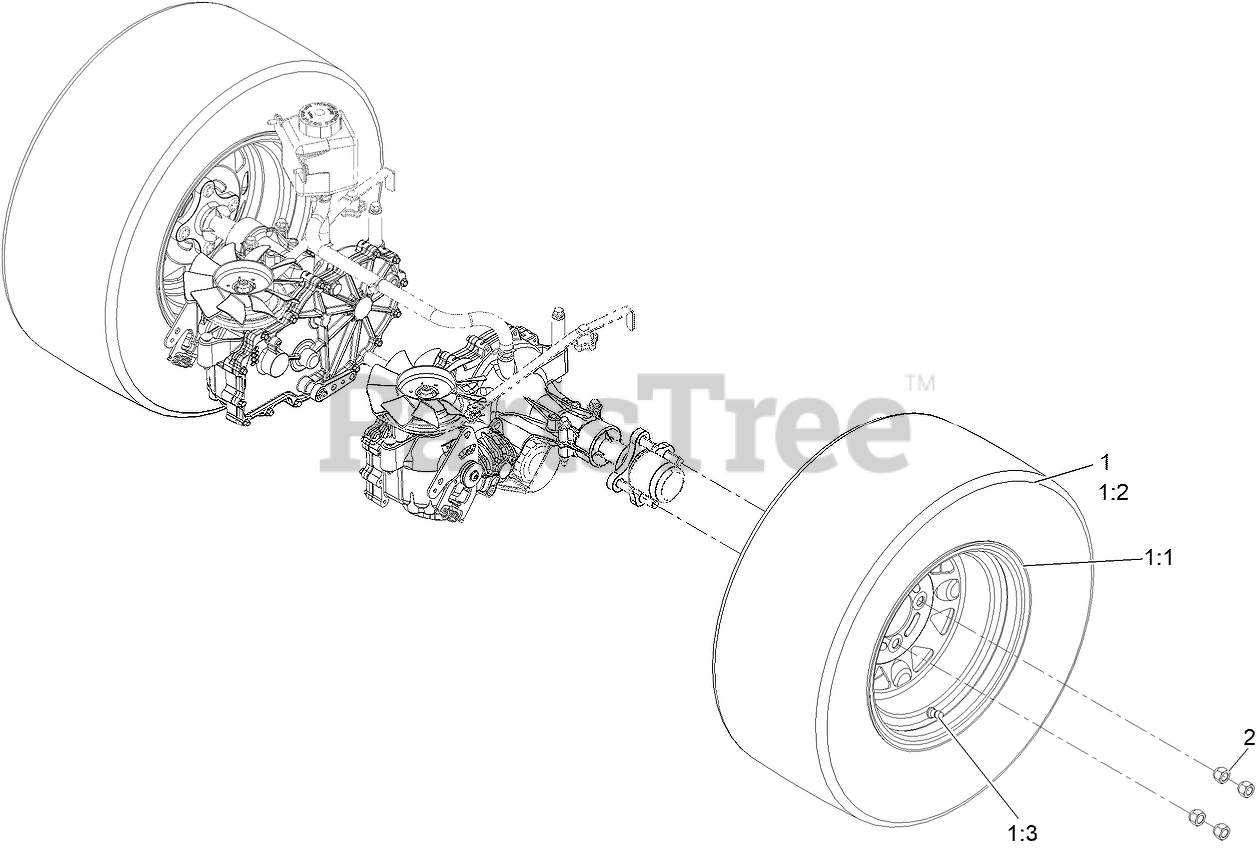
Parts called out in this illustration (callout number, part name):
1	WHEEL AND TIRE ASM
1:3	VALVE
2	NUT-LUG
